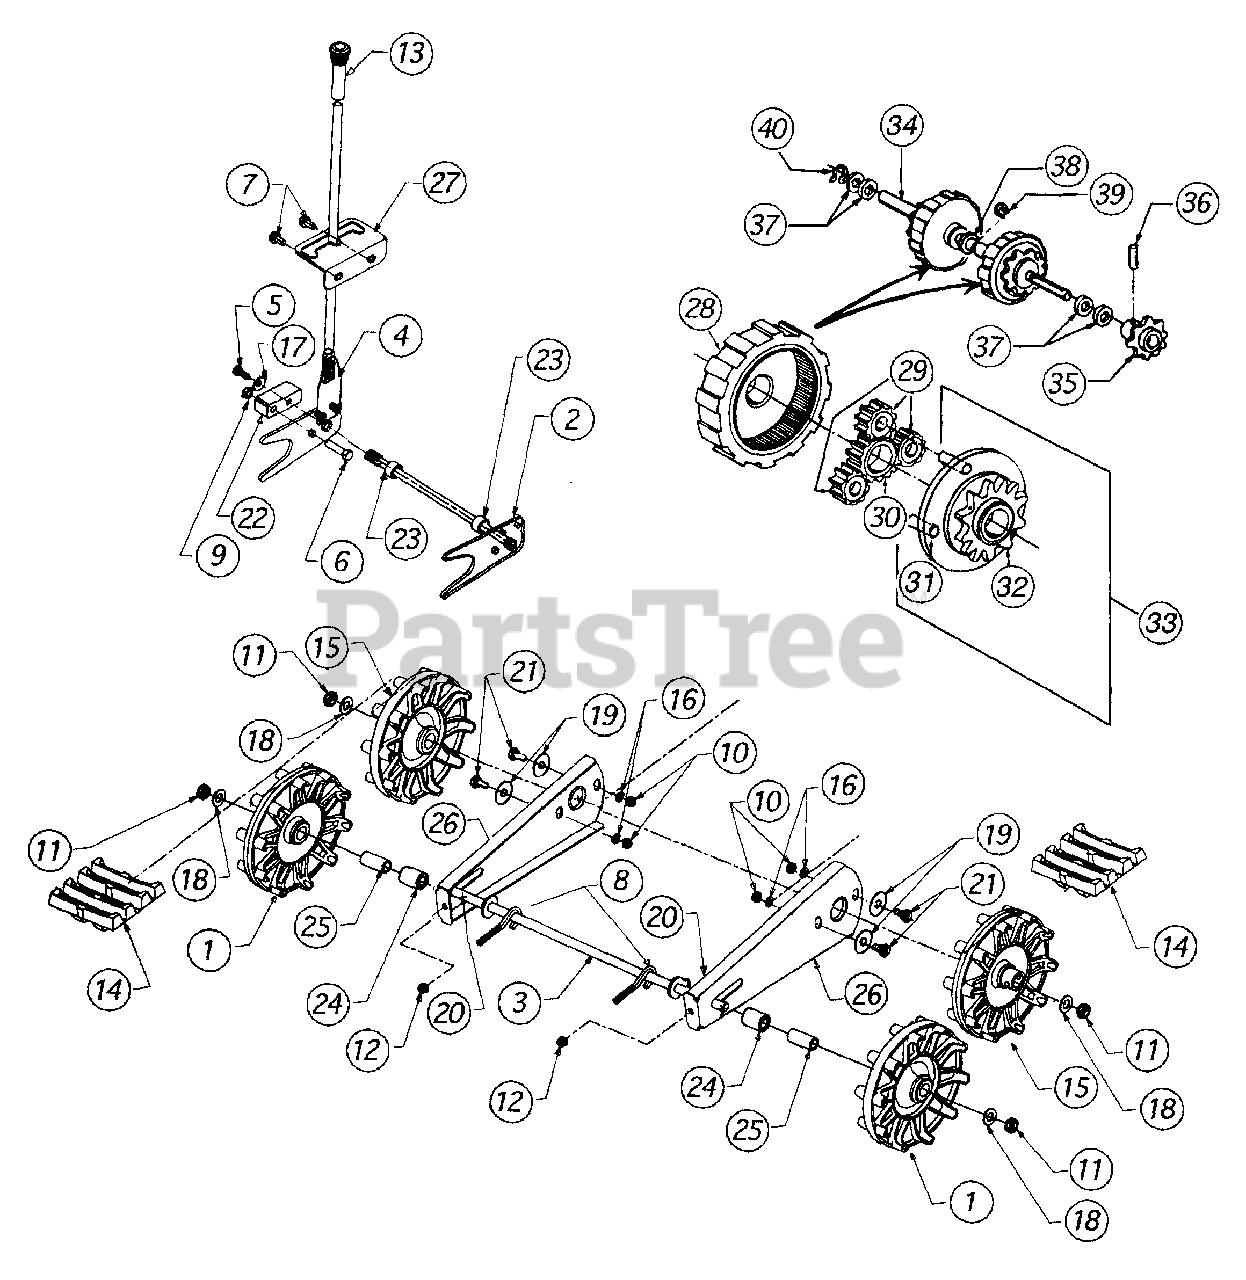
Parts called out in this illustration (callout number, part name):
1	Wheel Assembly Idler
5	Screw
6	Screw
7	Screw
8	Screw
9	Lock Nut
10	Hex Nut
11	Jam Nut
12	Hex Nut
14	Track
15	Wheel - Track Drive
16	Lock Washer
17	Bell Washer
18	Flat Washer
19	Flat Washer
20	Lubricant
21	Shoulder Screw
22	Lift - Shaft Drive
23	Spacer
24	Spacer
25	Spacer
26	Plate - Track Side
28	Gear Ring
29	Gear 12-Tooth
30	Gear 18-Tooth
31	Pin Dowel
32	Carrier
33	Carrier Assembly
34	Shaft - Track Drive
35	Sprocket - 13 Tooth
36	Spring Pin
37	Flat Washer
38	Flat Washer
39	Snap Ring .625" Shaft
40	Snap Ring .56" Shaft
